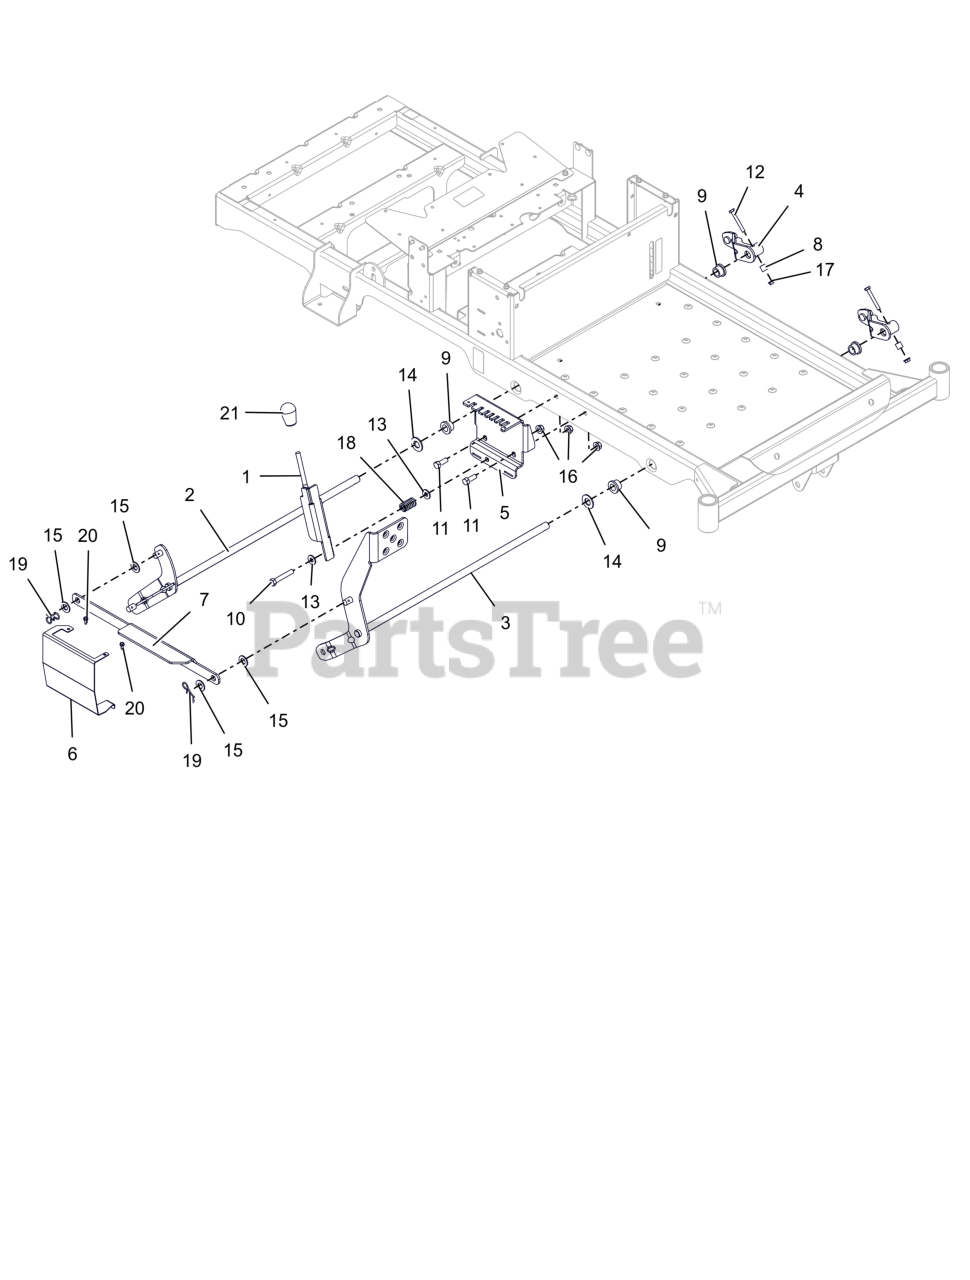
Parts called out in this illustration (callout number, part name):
1	WLDMT, HEIGHT OF CUT (ORANGE)
2	WLDMT, REAR DECK LIFT (ORANGE)
3	WLDMT, FOOTPEDAL (ORANGE)
4	WLDMT, DECK LIFT ARM (ORANGE)
5	PLATE, HEIGHT (ORANGE)
6	GUARD, DECK HOC (ORANGE)
7	LINK, LIFT /HOC (ORANGE)
8	BSHG-SLV .265X.500X.500
9	BSHG-FLG .629X.879X.469X1.250
10	BLT,HEX .38-16X2.25 G5 ZCC
11	BLT,HEX .38-16X1.00 G5 ZCC
12	BLT, HEX .25-20X2.00 G5 ZCC
13	WSHR,FLT .375X.875X.083 ZCC
14	WSHR, FLT .656X1.313X.095 ZCC
15	WSHR-FL-NYL .518X1.000X.080
16	NUT-LK-CTR-FLG .375-16 GF ZCC
17	NUT-LK-CTR-FLG .25-20 ZC120
18	SPRG, COMPRESSION
19	PIN, BOWTIE .091X1.875 ZCC
20	SCR,TAP #10-24X.50 HWH TR ZCC
21	KNOB,SOFT TEARDROP,PUSH-ON BLK
